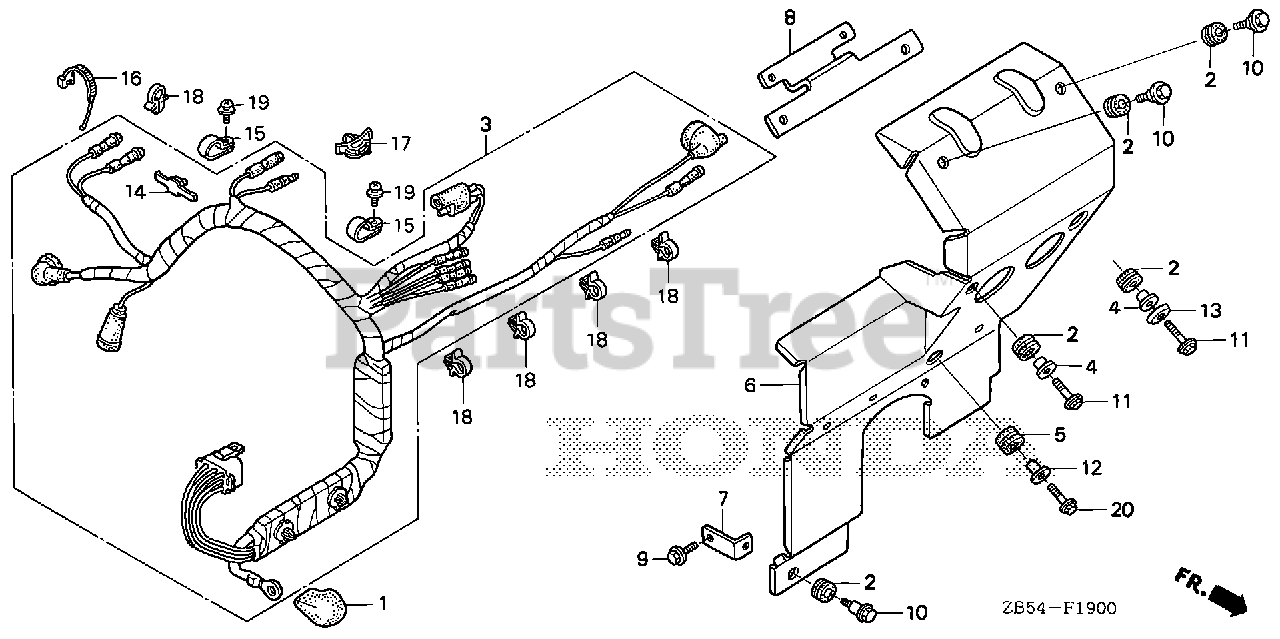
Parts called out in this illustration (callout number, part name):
1	CAP, THERMO SWITCH
2	RUBBER B, RADIATOR CAP MOUNTING
3	WIRE HARNESS ASSY.
4	COLLAR, TAILLIGHT
5	GROMMET, METER SETTING
6	COVER, SOUND-PROOF *TBLACK* (BLACK)
7	BRACKET, SOUND-PROOF
8	STAY, SOUND-PROOF COVER
9	BOLT, FLANGE (6X12) (CT200)
10	BOLT, FLANGE (6MM)
11	BOLT, FLANGE (6X20)
12	COLLAR (8MM)
13	WASHER, AIR CLEANER
14	CLIP, WIRE HARNESS (Honda Code 1685387). (BLUE)(HARNESS TAPING)
15	CLIP (14MM)
16	TIE, CABLE (NATURAL 154X3.4)
17	CLIP, CORD
18	CLIP B, CABLE
19	SCREW-WASHER (5X12)
20	BOLT, FLANGE (8X30)
